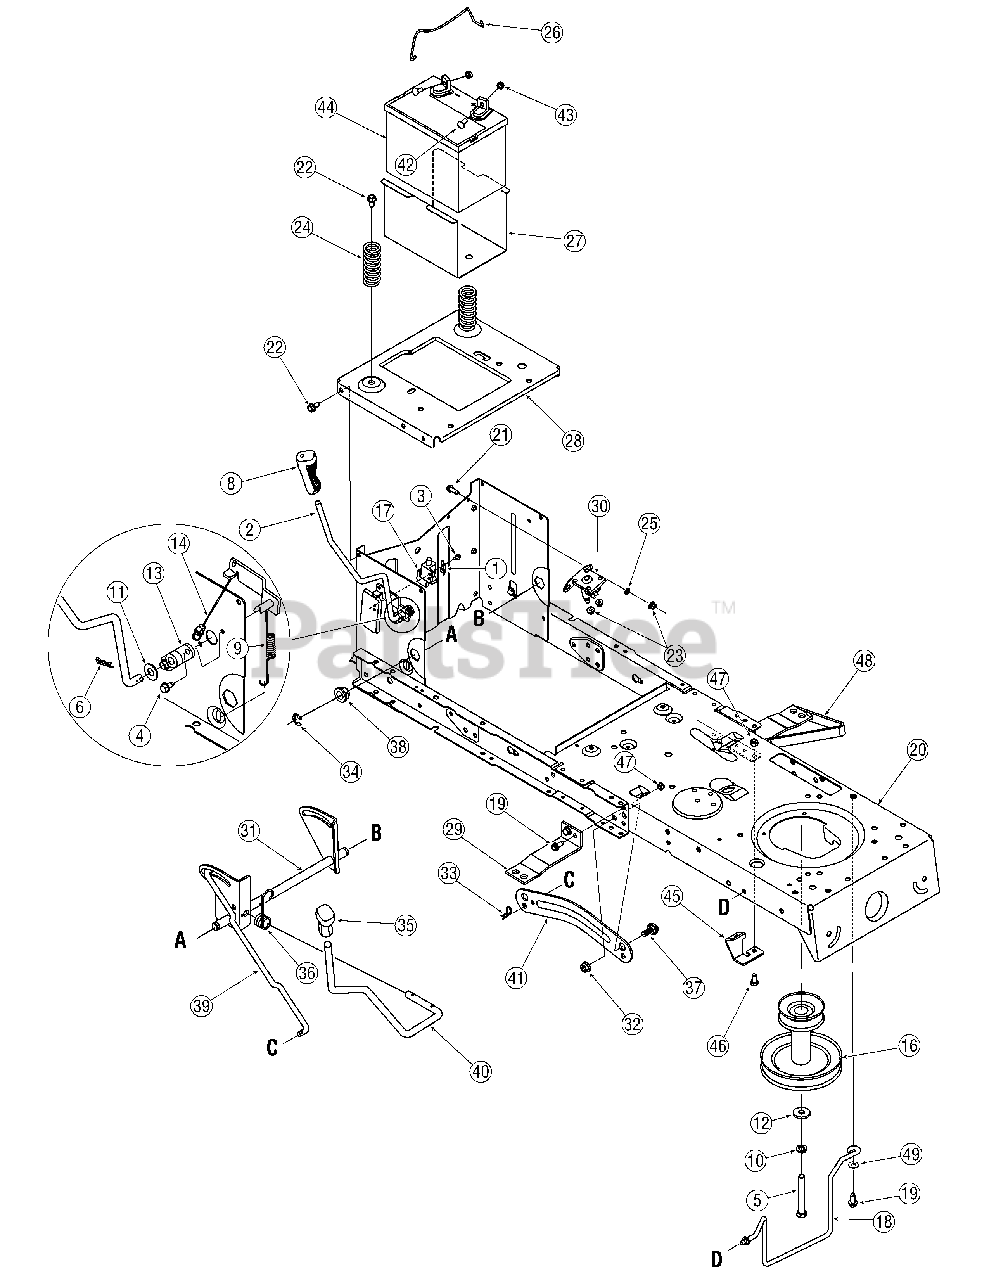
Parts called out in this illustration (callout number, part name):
1	Plate, Switch
3	Screw, #10-16, 0.500
4	Screw, 1/4-20, 0.500
5	Screw, 7/16-20, 3.25, Gr5
6	Pin, Cotter, .072 Dia. x 1.13
7	Pin, Click, .092 x 1.64
8	Grip, Handle, 3/8
9	Spring, Extension
10	Washer, Lock, 7/16
11	Washer, Flat, .406 x .875 x .059
12	Washer, Flat, .450 x 1.250 x .164
13	Bearing, PTO
14	Cable, Deck Engagement
16	Engine Pulley, 3.56 x 6.12 Dia. Hydro
17	Switch, Interlock
18	Rod, Belt Keeper (38-inch Deck)
18	Rod, Belt Keeper (42-inch Deck)
19	Screw, 5/16-18, .750
21	Screw, 1/4-20, 0.750
22	Screw, 5/16-18, 0.625
23	Nut, Flange Lock, 1/4-20, GrF, Nylon
24	Spring, Compression, 1.28 OD x 3.125
25	Washer, Lock, 1/4
30	Solenoid
32	Nut, Flange Lock, 3/8-16, GrF, Nylon
33	Bow Tie Cotter Pin
34	Ring, E-Type, .625 Dia.
35	Grip, Handle, 1/2
36	Spring, Torsion
37	Screw, Shoulder, .625 x .175, 3/8-16
38	Bearing, Hex Flange
40	Deck Handle, Lift
42	Screw, Carriage, 1/4-20, .75, Gr5
43	Nut, Sems, 1/4-20
44	Battery, 190 CCA (Single Cylinder Engine)
44	Battery, 270 CCA (Twin Cylinder Engine)
46	Screw, 5/16-18, 0.625, Gr5
47	Nut, Hex Lock, 5/16-18, Nylon
